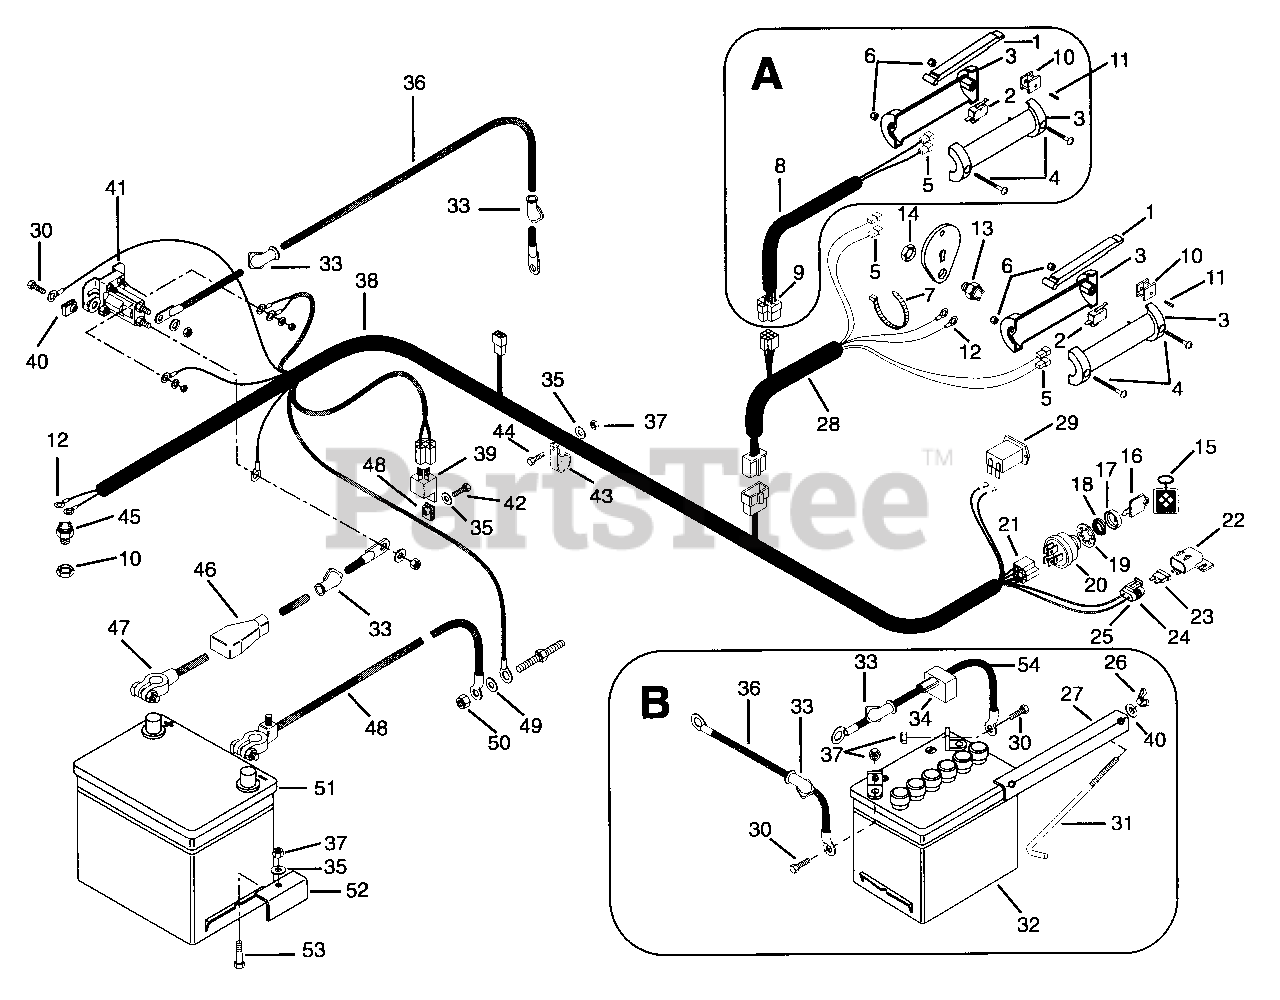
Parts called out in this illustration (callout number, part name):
1	Lever
2	Switch
3	Handle, Left Hand & Right Hand
4	Screw-Machine 10-24 x 1.50
5	Terminal, Female
6	Nut-Locking-Nylon 10-24
7	Tie Wrap, Black
8	Harness, Steering Brake
9	Connector
10	Holder, Switch
11	Pin-Roll .094 x .750
12	Terminal, Eyelet
13	Switch, Interlock Closed
14	Nut-Stamped .56-18
15	Key Chain
16	Ignition Switch Key
17	Cap-Ignition Switch
18	Nut-Panel .562-24
19	Washer-Lock Internal .563 x .040
20	Ignition Switch
21	Connector
22	Cover
23	Fuse, 25 AMP
24	Terminal For 10-12 Gauge Wire
25	Assembly, Connector Weather Tight
26	Nut-Wing .250-20
27	Hold Down
28	Harness, Wiring Handlebar
29	Hour meter
30	Bolt-Hex .25-20 x .63
31	Tie Down
32	12 Volt Battery
33	Boot, Insulator
34	Insulator
35	Washer-Flat-Steel .281 x .620 x .065
36	Cable, Battery to Solonoid 8 HP
36	Cable, Ground
37	Nut-Locking-Center .25-20
38	Harness, 10, 12 & 16-HP Electric
38	Harness, 8-HP Electric
38	Harness, 16-HP Electric
39	Relay
40	Nut-Speed .25-02
41	Solenoid
42	Bolt-Hex .25-20 x .63
43	Clamp, Cushioned Steel
44	Bolt-Hex .25-20 x .75 Grade 5
45	Switch, Interlock Open
46	Cover, Battery Terminal
47	Cable, Positive Battery
47	Cable, Battery-To-Magneto
48	Cable, Negative Battery
49	Washer-Flat-Steel .406 x .812 x .065
50	Nut-Locking-Center .375-16 Grade 2
51	Battery, 12 Volt
52	Clamp
53	Bolt-Round Head Square Neck .25-20 x 1.75
54	Cable, Battery to Solonoid
